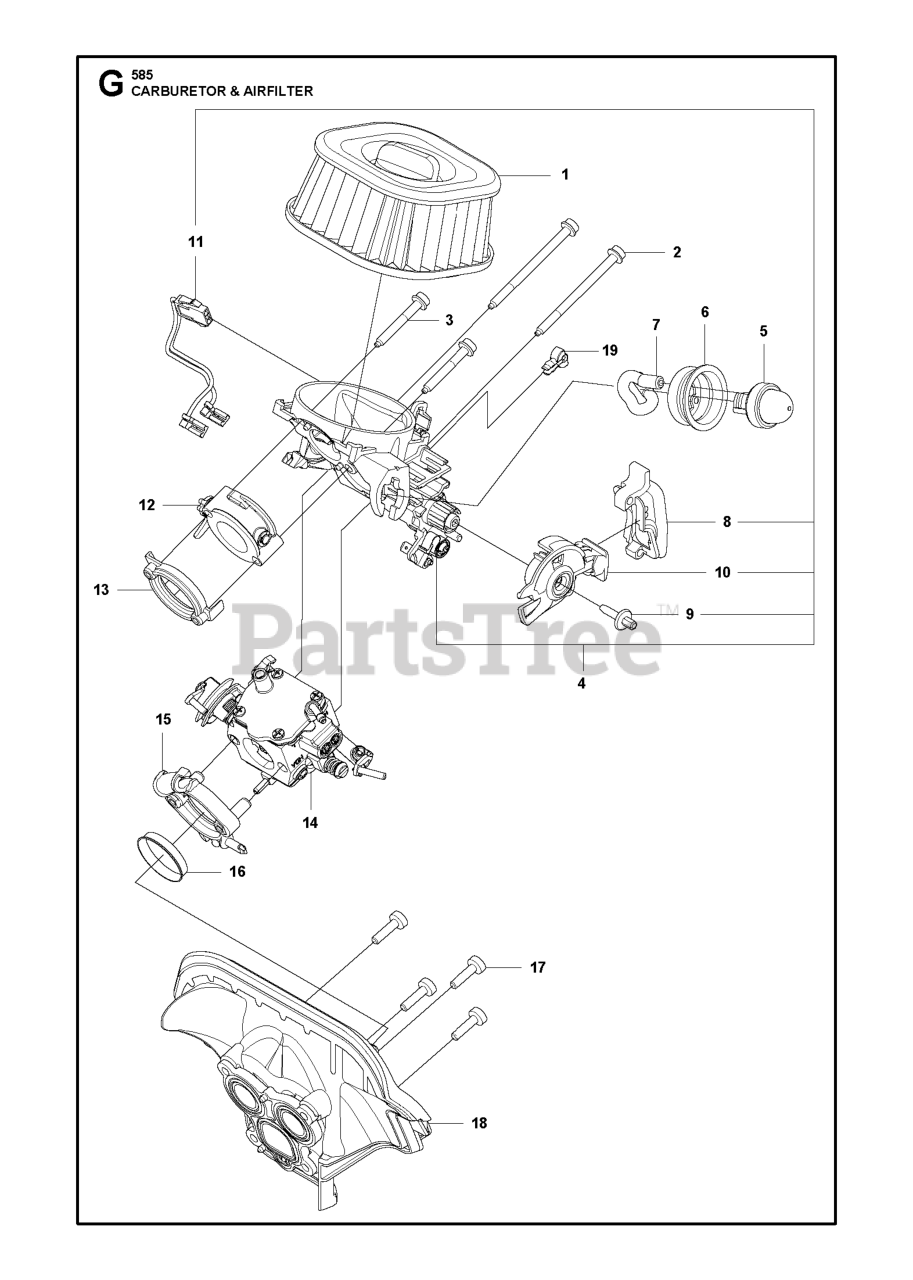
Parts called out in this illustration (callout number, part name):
1	AIR FILTER ASSY MESH 50 MICRO
1	AIR FILTER ASSY MESH 27 MICRO
1	AIR FILTER ASSY MESH NW
2	SCREW INTERNAL TORX HEAD FLANG
3	SCREW INTERNAL TORX HEAD FLANG
4	INLET ELBOW
5	AIR CLEANER ZAMA
6	SEALING PURGE
8	SEALING CHOKE CONTROL
10	CHOKE CONTROL ASSY DETENT CHO
11	WIRING ASSY STOP
12	VALVE HOUSING ASSY
13	FLANGE VALVE HOUSING
14	CARBURETTOR HDA-351B
15	FLANGE CARBURETTOR ASSY
16	SLEEVE INLET PIPE
17	SCREW ITXSCM M4X15 T27 12.9 T
18	INLET PIPE ASSY
